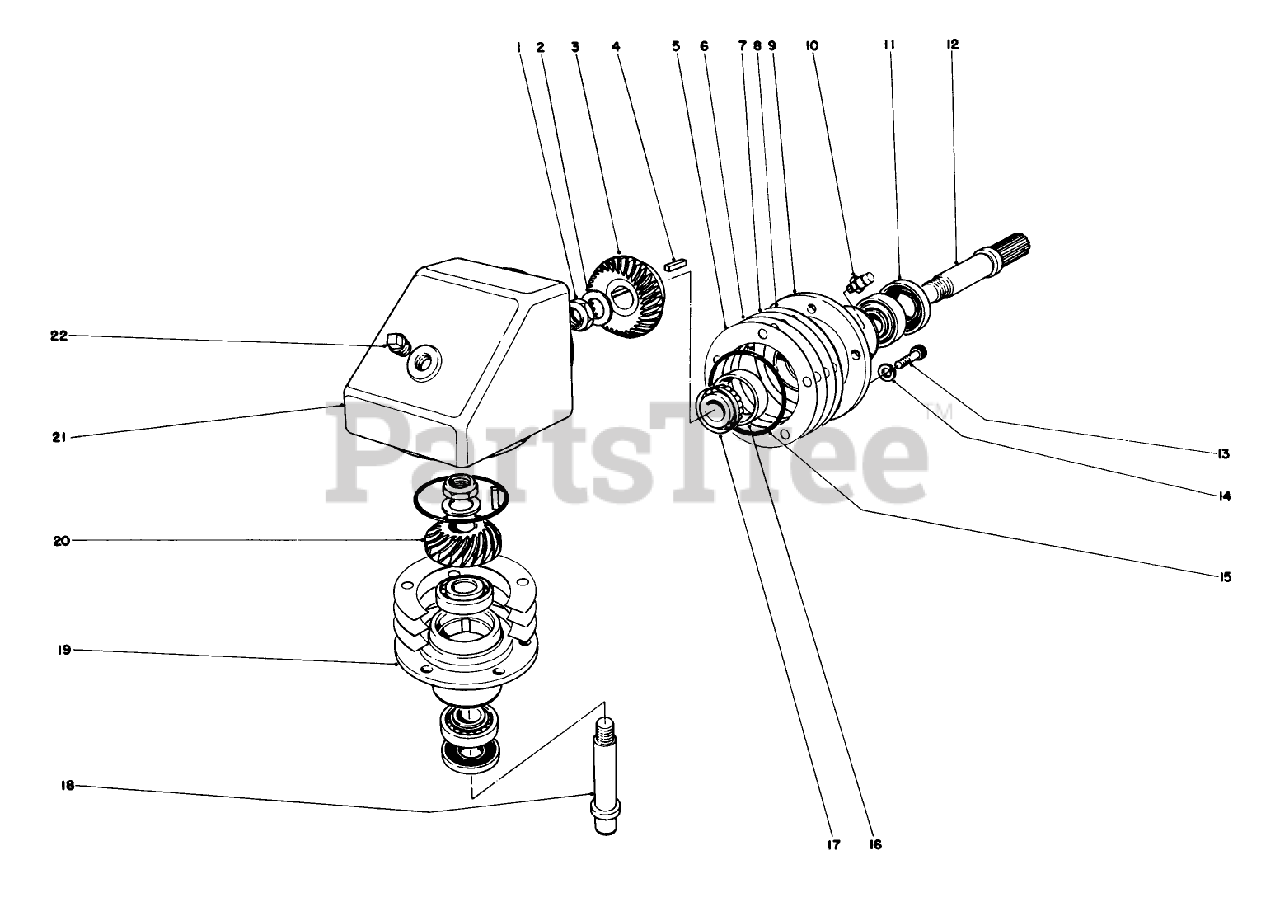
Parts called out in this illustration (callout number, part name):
1	NUT-LOCK, NI
2	THRUST WASHER
4	KEY-SQUARE
5	.002 SHIM (RED)
6	.005 SHIM (BLUE)
7	.015 SHIM (PINK)
9	INPUT BRG HSG
11	OIL SEAL
12	INPUT SHAFT
13	SCREW-HSH
14	WASHER-LOCK
15	O-RING
16	BEARING-CUP
17	CONE-BEARING
18	OUTPUT SHAFT
19	OUTPUT BRG HSG
20	PINION
21	GEAR BOX
22	3/8-18 SQ HD PLUG/MAG
